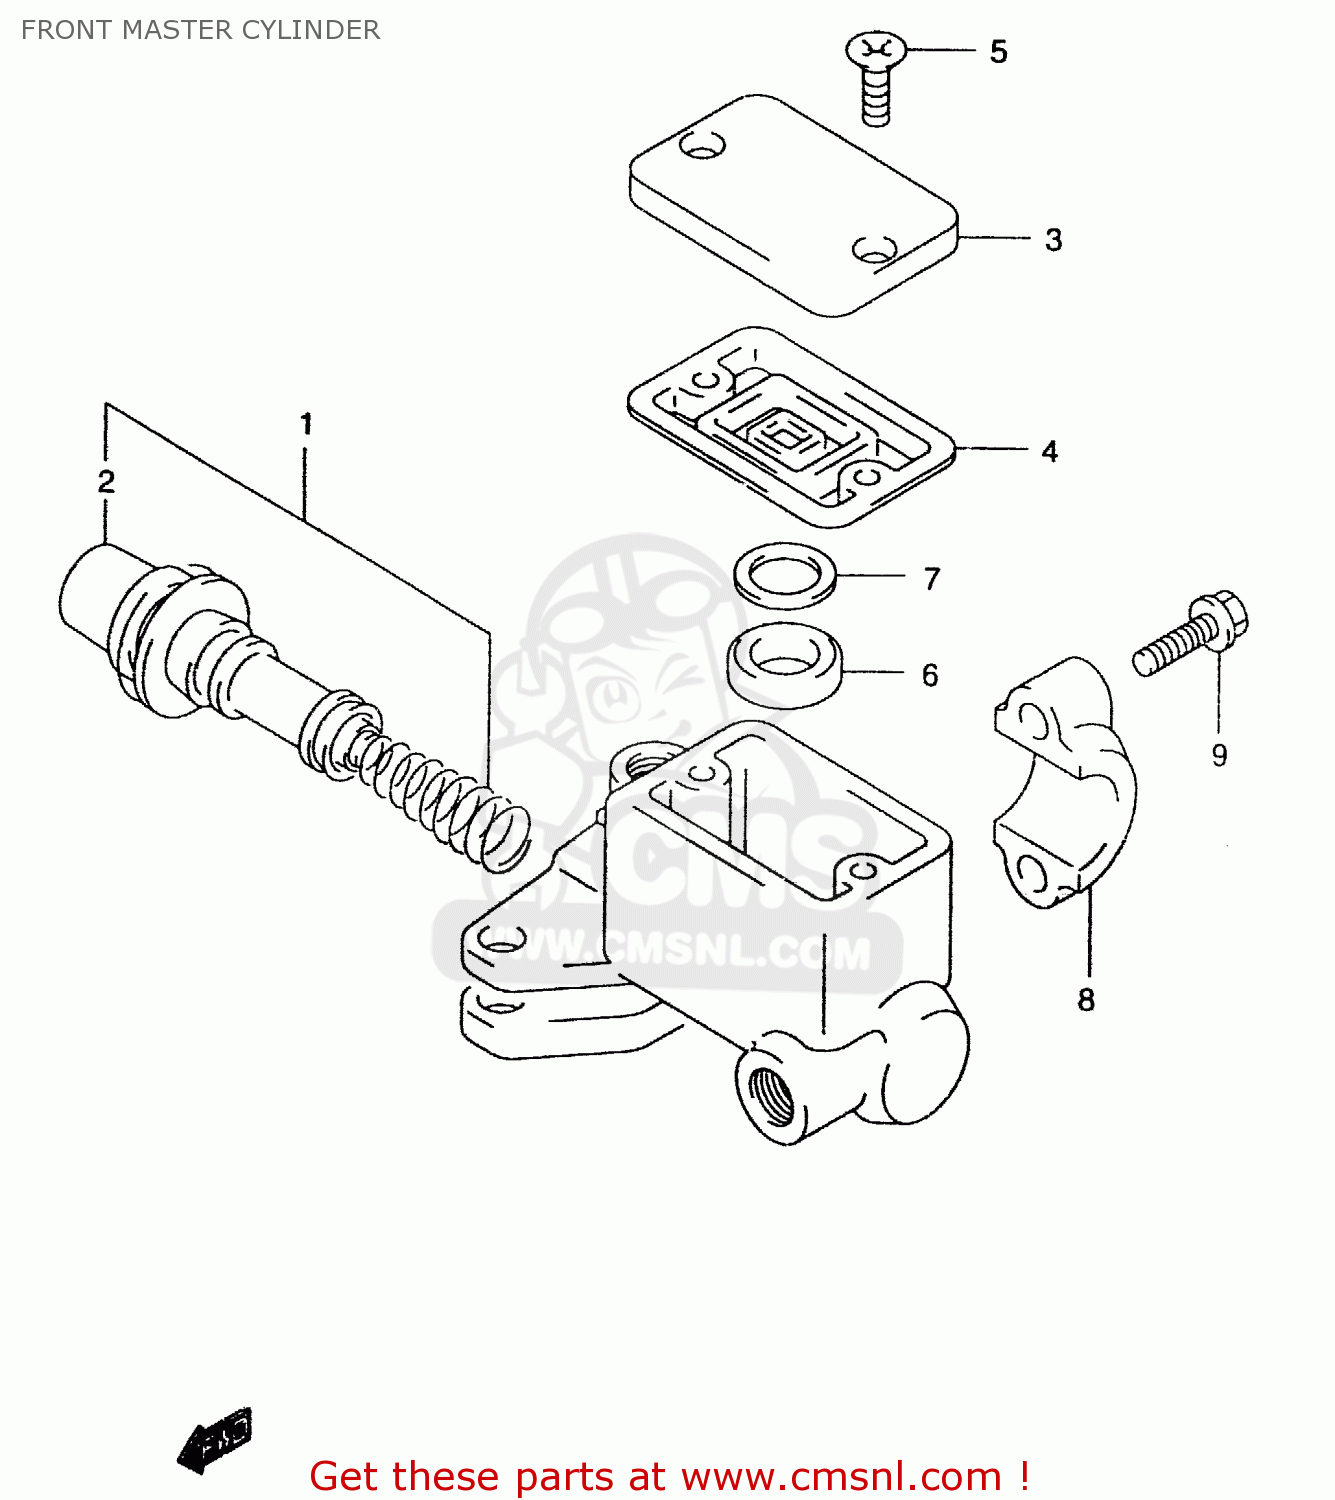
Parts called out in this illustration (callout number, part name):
1	PISTON & CUP SET
2	BOOT
3	CAP
4	DIAPHRAGM
5	SCREW
6	SEPERATOR
7	PLATE
8	HOLDER
9	BOLT(6X22)
